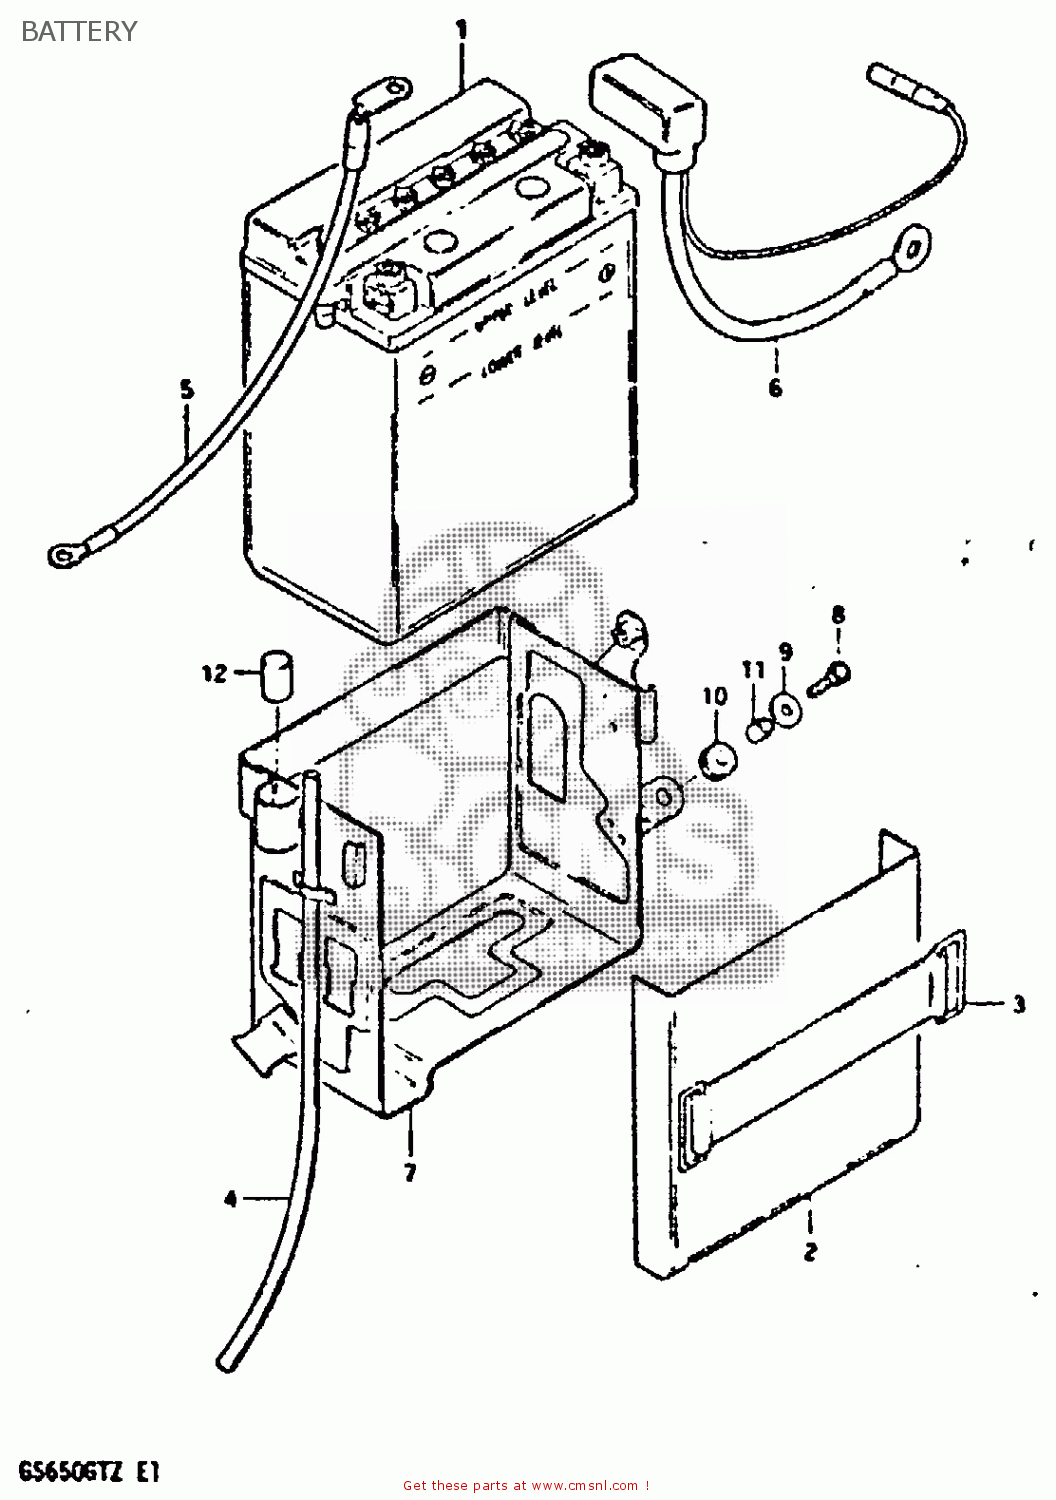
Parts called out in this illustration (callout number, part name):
1	BATTERY ASSY (12V)
2	COVER,BATTERY
3	BAND
4	HOSE,BATTERY EXHAUST
5	CORD,BATTERY MINUS
6	CORD,BATTERY PLUS
7	HOLDER,BATTERY
8	BOLT, UPPER
9	WASHER
10	CUSHION
11	SPACER(6.1X9X7.5)
12	CUSHION
